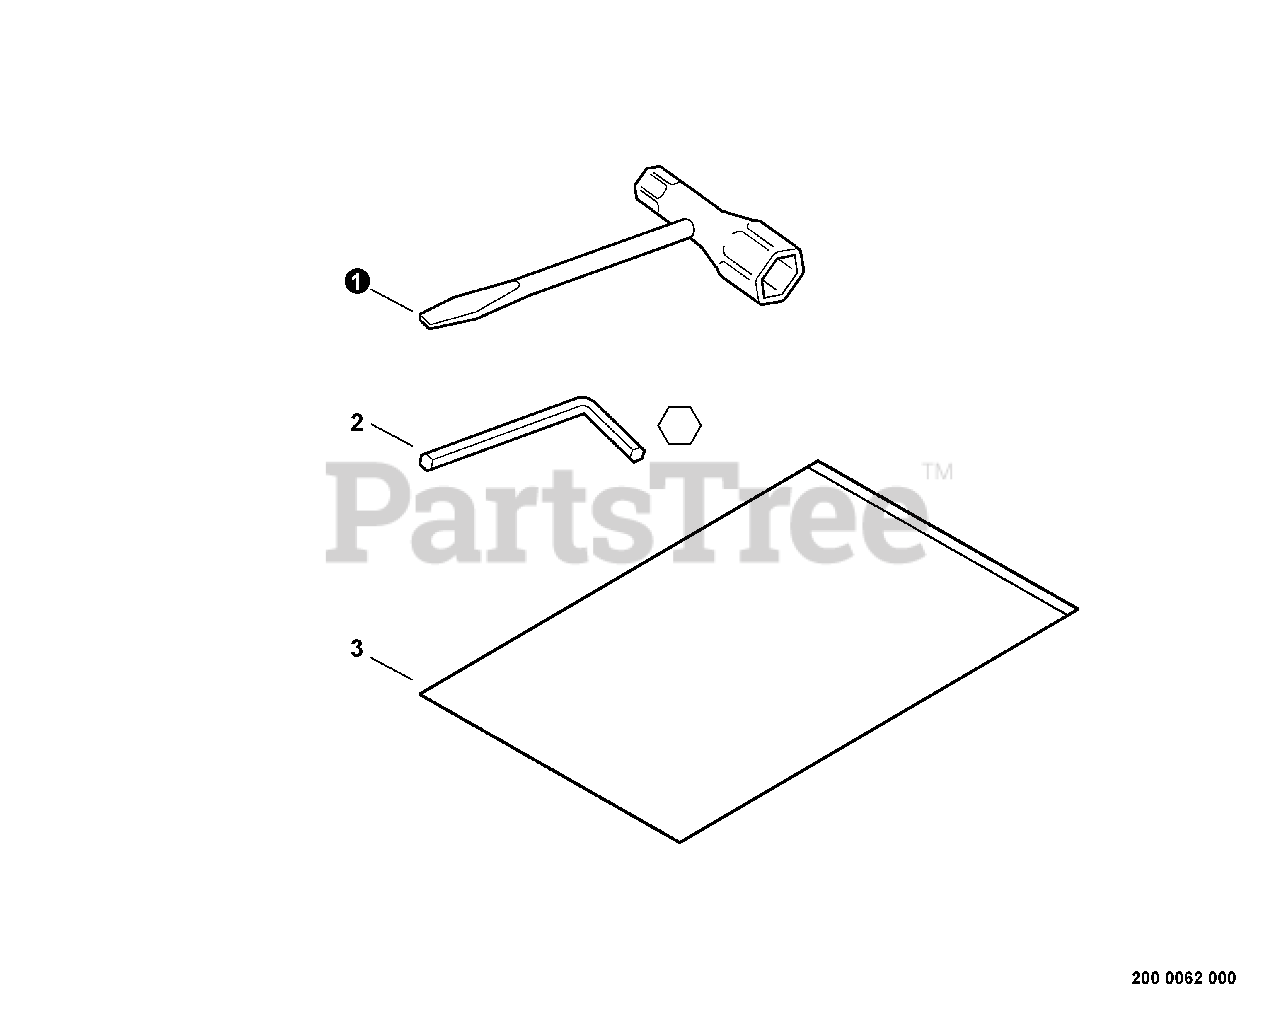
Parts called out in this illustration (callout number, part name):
1	T-WRENCH - 13X16mm
2	HEX KEY - 4mm
3	BAG, TOOL
